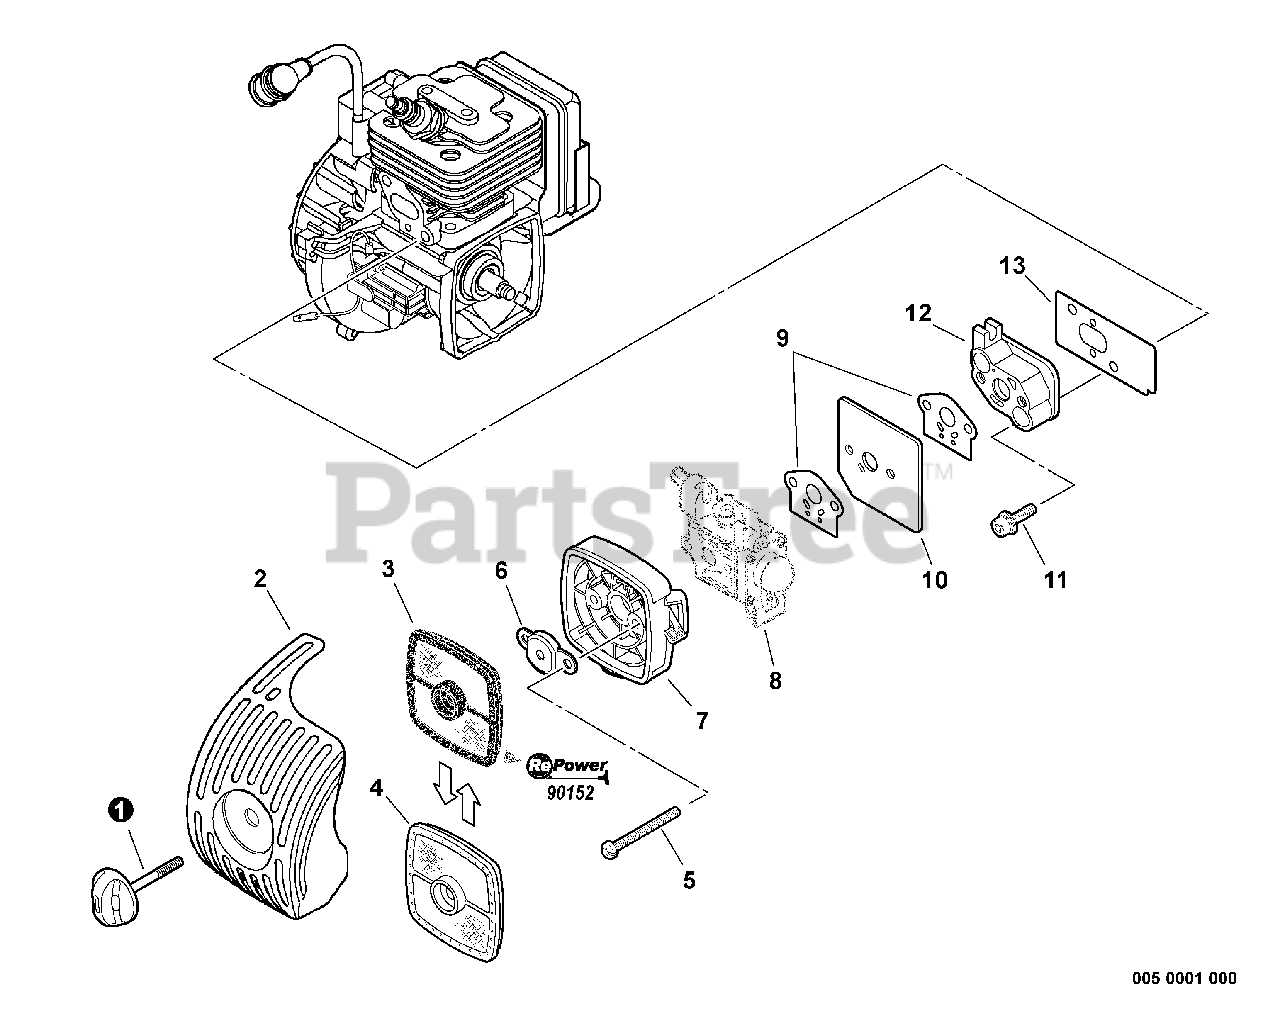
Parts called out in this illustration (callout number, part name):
1	THUMBSCREW
2	COVER, AIR FILTER
3	FILTER, AIR - DOUBLE LAYER
4	FILTER, AIR - SINGLE LAYER
5	SCREW 5×65
6	PLATE, PREVENT
7	CASE, AIR FILTER - BLACK
8	CARBURETOR
9	GASKET, INTAKE
10	PLATE, INSULATOR
11	BOLT 5×25
12	INSULATOR, INTAKE
13	HEAT SHIELD, INTAKE
14	TUNE-UP KIT - REPOWER
